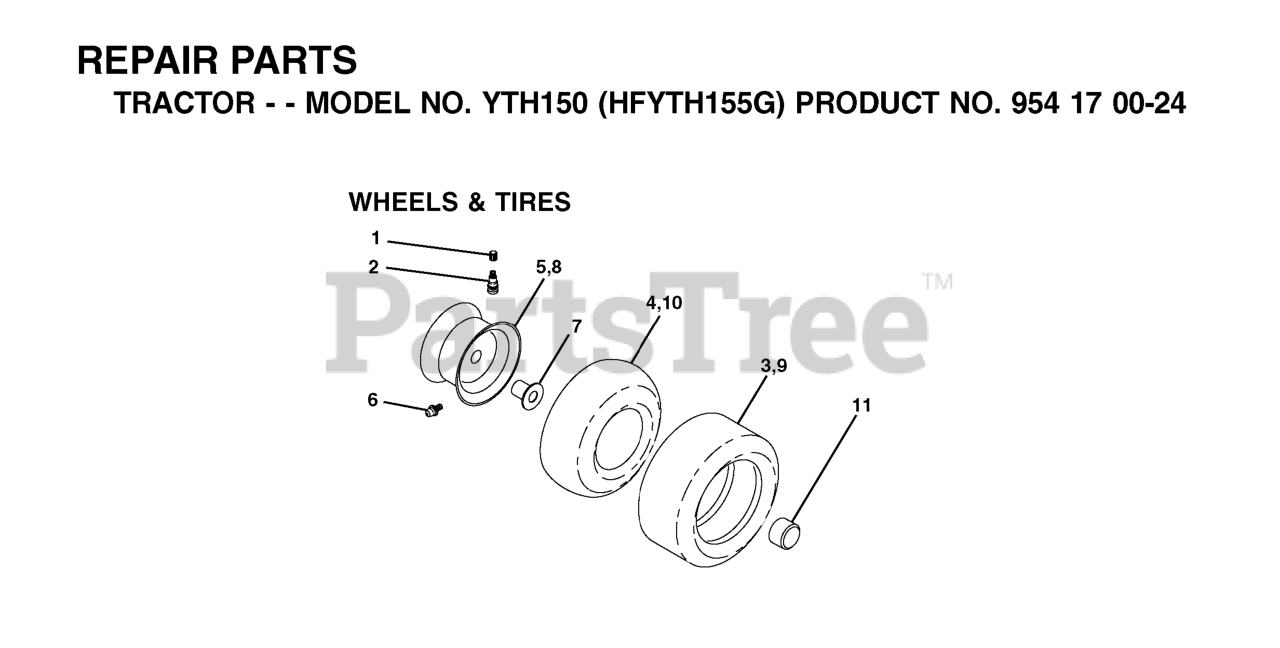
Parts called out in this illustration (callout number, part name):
2	VALVE STEM LT
3	TIRE HEAVY DUTY
4	TUBE.5.3/4.5/6
5	RIM ASM 6" FRONT SILVER
6	FITTING LT
7	BEARING T
8	RIM ASM 8" REAR SILVER
9	TIRE.TS.20X10-8
10	TUBE
11	CAP, AXLE BLK
